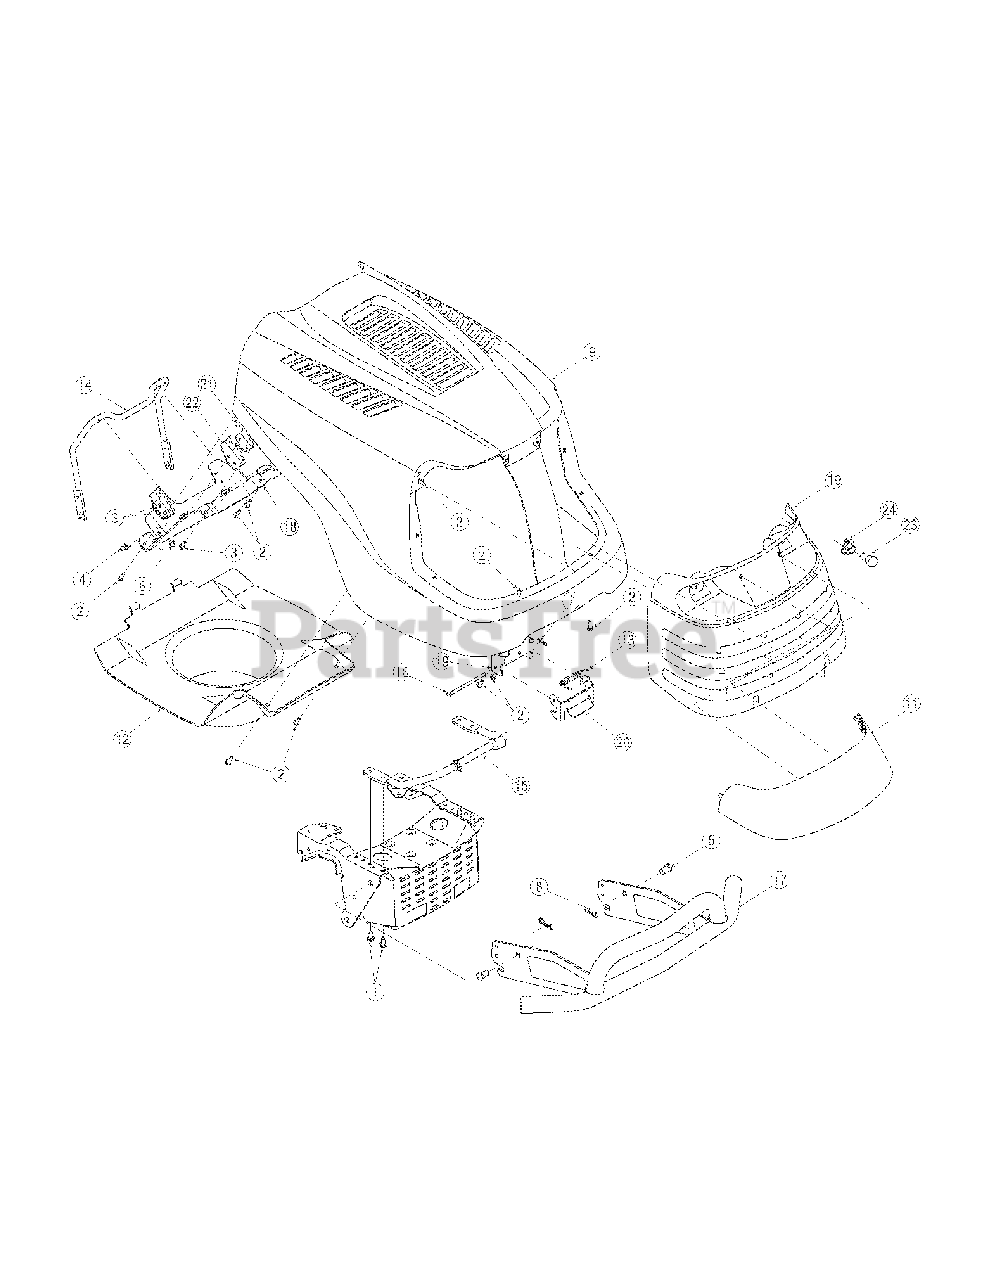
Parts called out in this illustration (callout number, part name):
1	Screw, 5/16-12 x.750
2	Screw, 1/4-15 x.750
3	Screw, Self Tapp, 1/4-20 x.750
4	Screw, Ball, 5/16-18 x.56
5	Pin, Clevis,.50 Dia. x.78 Lg.
6	Nut, Flange Lock, 5/16-18
7	Pin, Cotter,.072 Dia. x 1.13 Lg.
8	Pin, Click,.092 x 1.64 Lg.
9	Hood
9	Push Nut .25ID x .50 OD
9	Screw, Hi Low 5/16-14 x .75
10	Grill
11	Lens
12	Hood Plenum
13	Latch Spring
14	Hood Pivot Rod
15	Hood Latch Rod
16	Rod,.250 Dia. x 4.55 Lg.
20	Latch Pivot Bracket
21	Upper Pivot Bracket
22	Hood Pivot Bracket
23	Miniature Lamp, 12V
24	Lamp Socket
